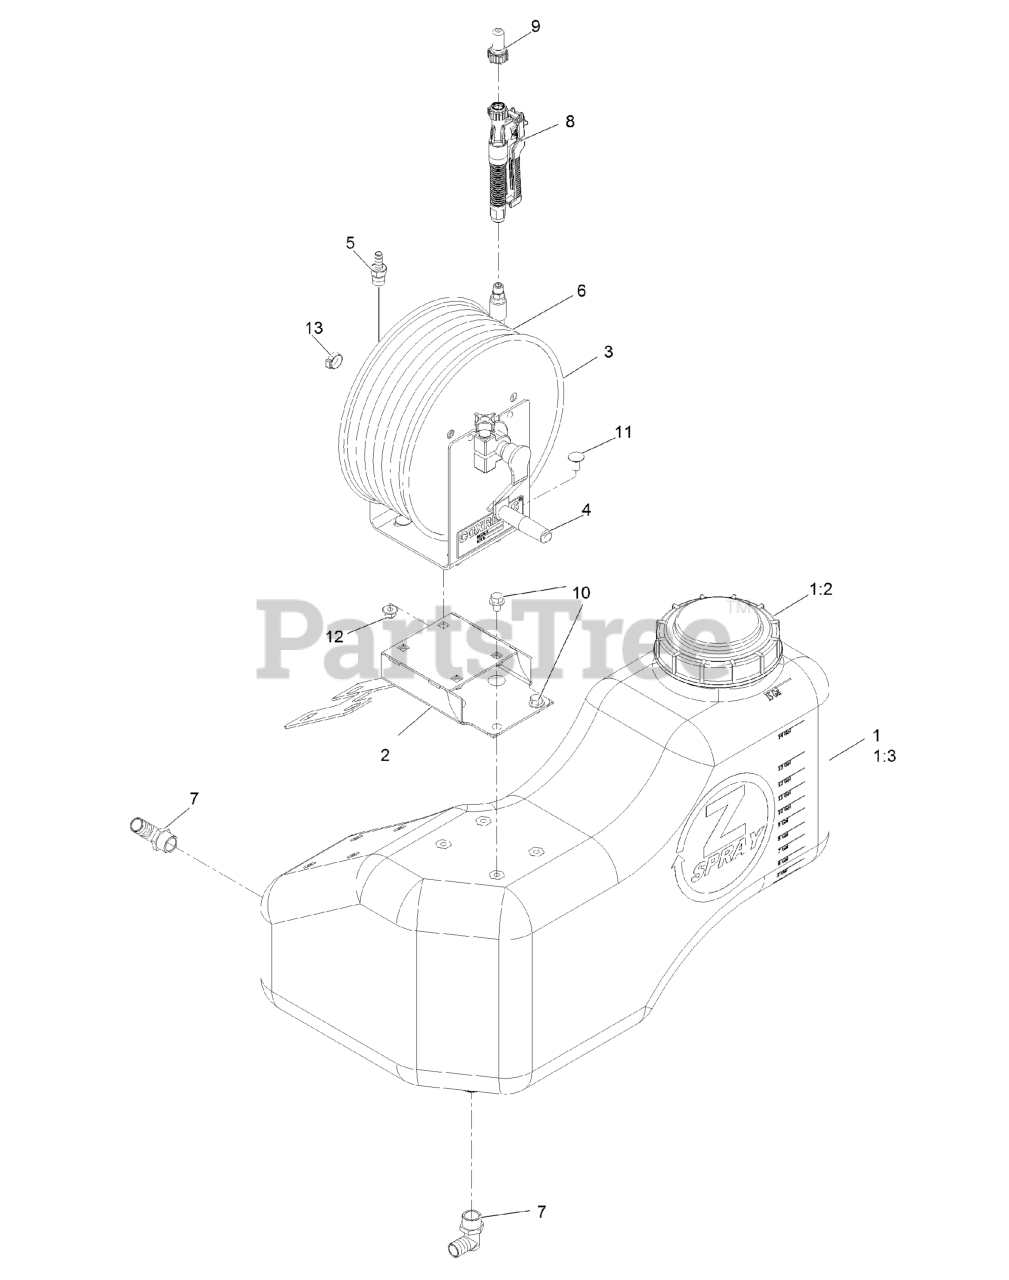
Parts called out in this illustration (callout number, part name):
1	ASM-TANK, LT
1:2	CAP-TANK, SPRAY
1:3	FITTING-BULKHEAD
2	MOUNT-REEL, HOSE
3	REEL-HOSE
4	Crank-Reel
5	FITTING,MALE
6	HOSE-SPRAY, 75'
7	FITTING-ELBOW, 90
8	GUN-SPRAY, SPOT
9	TIP-SPRAY, #12 SPOT
10	Screw-HHF
11	SCREW-CARRIAGE
12	Nut-Hex Flange
13	CLAMP-OETIKER, 167
